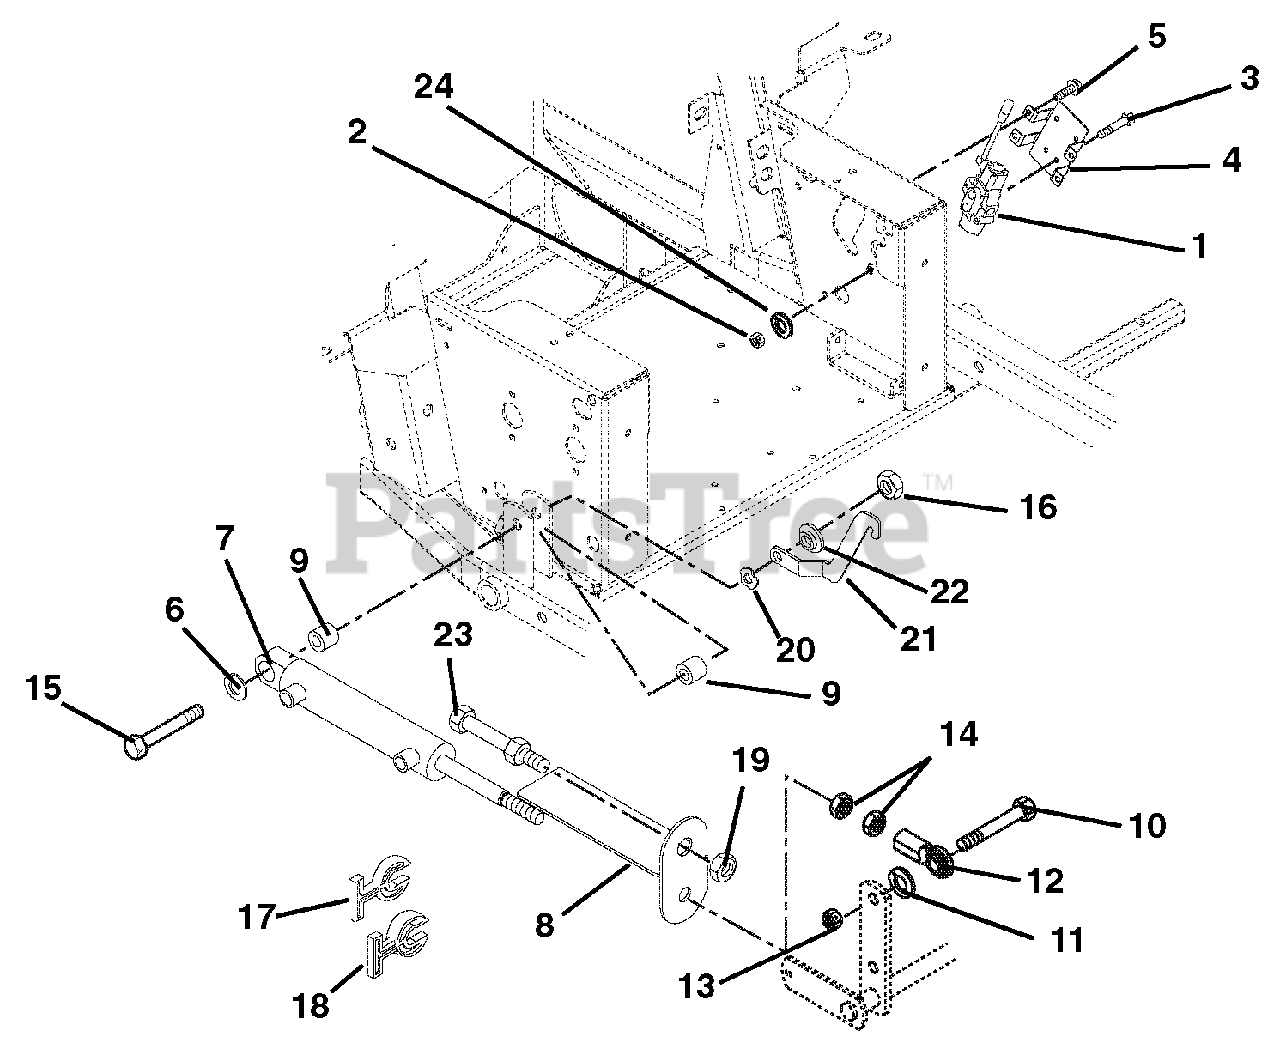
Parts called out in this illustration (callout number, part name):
1	Valve, Hydraulic
2	Nut, Locking Center .31-18
3	Bolt, Hex .31-18 x 2.00 Grade 5
4	Bracket, Valve Mounting
5	Screw, Tapping .38-16 x .50 Hex Washer Head
6	Washer, Flat Steel .515 x 1.625 x .25
7	Cylinder, Lift
8	Strap, Height of Cut Indicator
9	Bushing .516 x 1.00 x 1.05
10	Bolt, Hex .62-11 x 2.25 Grade 8
11	Washer, Lock .62 x .156
12	Rod End, Right Hand Female .625
13	Nut, Locking Center .62-11
14	Nut, Jam .625-18
15	Bolt, Hex .50-13 x 3.75 Grade 5
16	Nut, Locking Top Flange .50-13
17	Stop, Cylinder .34 Thick
18	Stop, Cylinder .68 Thick
19	Nut, Jam .75-16
20	Washer, Wave .076 x 1.12 x .08
21	Latch, Floor Board
22	Bushing, Flange .515 x .75 x .275 x 1.12
24	Washer, Lock .31 x .078 Reg
